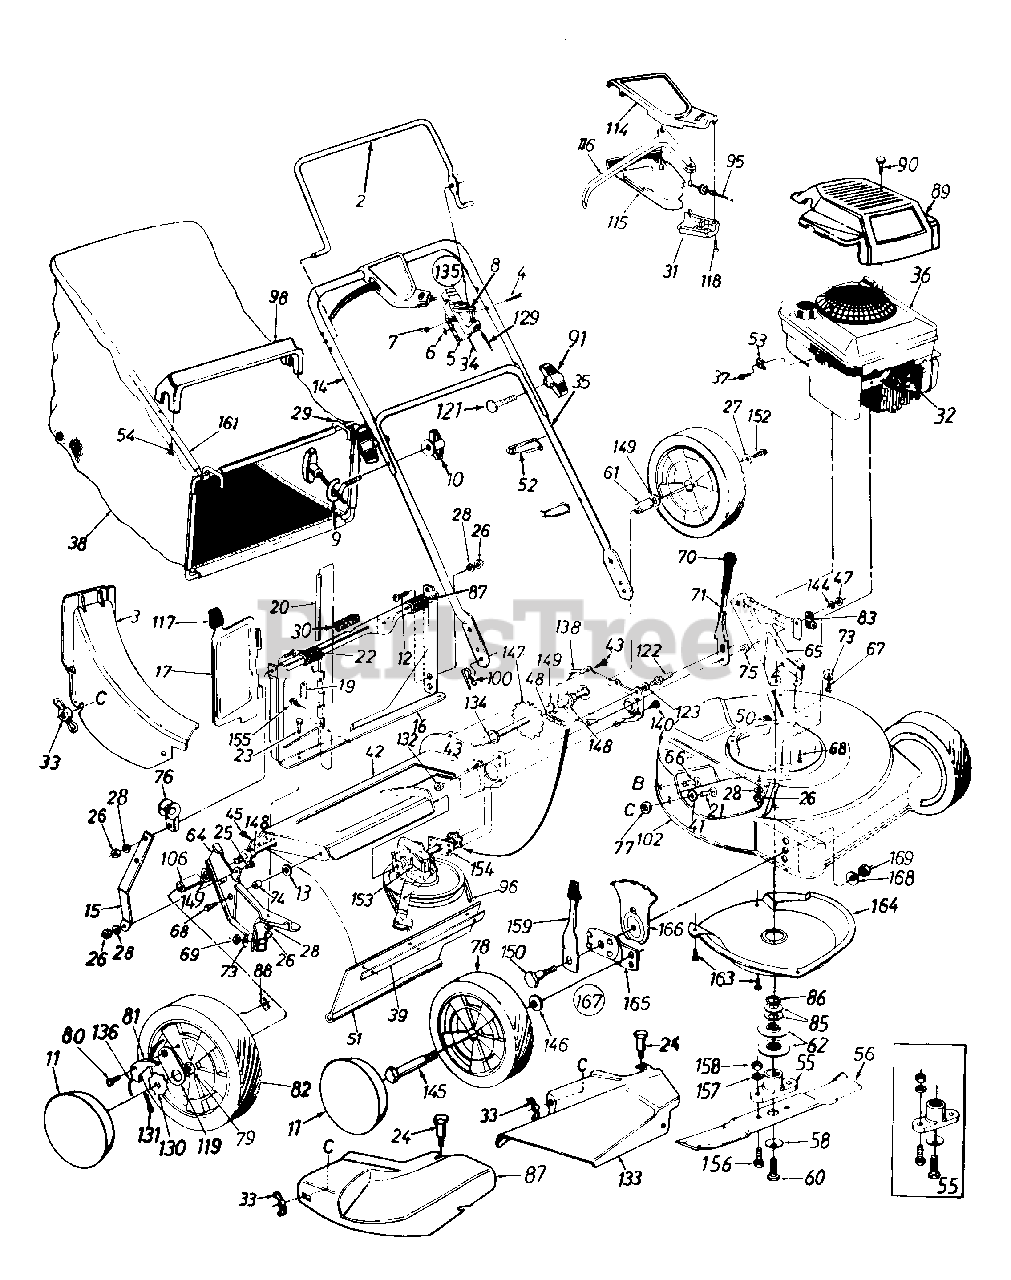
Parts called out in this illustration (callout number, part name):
3	Rear Discharge Chute Ass'y.
4	Oval C-Sunk Scr.
5	Throttle Body
6	Spr. Wash..66" I.D.
7	Hex L-Nut 1/4-20 Thd.
8	Throttle Lever
9	Rope Guide
10	Wing Nut 1/4-20 Thd.
11	Hub Cap
12	Truss Mach. Scr. 1/4-20 x .62"
13	Fl-Wash..383" I.D. x 1" O.D.
19	Torsion Spring
20	Pivot Pin
21	Carriage Bolt 1/4-20 x .62"
22	Truss Mach. Scr. 1/4-20 x 3/4"
23	Hex Bolt 1/4-20 x .50" Lg.
24	Shoulder Bolt .312 Dia. x .18 Lg.
25	Hex Bolt 1/4-20 x .62" Lg.
26	Hex Nut 1/4-20 Thd.
27	Bell-Wash. 1/4" I.D.
28	L-Wash. 1/4" I.D.
30	Foam Strip
31	S.P. Control Cover
32	Spark Plug Insulator
33	Wing Nut w/Washer
34	Throttle Control Wire 61"
37	Hex Self-Tap Scr. #10-32 x .62"
38	Grass Bag
39	Retaining Strip
41	Fl-Wash..344" I.D. x.62"
42	Chain - Axle Ass'y.
43	Hex 8-Tap Scr. 1/4" x .38" Lg.
45	Hex AB-Tap Scr. 1/4 x .62"
47	Hex Patch L-Nut 3/8-24 Thd.
48	#48 Chain .500" Pitch x 30 Links
51	Rear Flap 3.75" x 17.30" Lg.
52	Cable Tie
53	Cable Clamp
54	Hex AB Scr. #12 x 1.25" Lg.
55	Blade Adapter Kit
56	21" Mulching Blade
58	Bell-Wash..46" I.D.
60	Hex Bolt 3/8-24 x 1.5" Lg. (Grade 5)
61	Spacer .513" I.D. x .703" O.D. x .69" Lg.
62	Pulley Half O.D. x .69" Lg.
64	R.H. Handle Wheel Brkt. Ass'y.
65	L.H. Handle Wheel Brkt. Ass'y.
66	Carriage Bolt 5/16-18 x .62"
67	Hex Wash. Hd. B-Tap Scr. 5/16-18
68	Hex Wash. Hd. TT-Tap Scr. 3/8-16
69	Hex Nut 5/16-18 Thd.
71	Height Adj. Lever
73	Bell-Wash. 5/16" I.D.
74	Spacer
75	Shld. Spacer .500" Dia.
76	Rope Guide
77	Bolt Retainer 1/4 x .50" O.D.
78	Front Wheel Ass'y. Comp.
79	Bearing 1/2" I.D.
80	Shld. Scr..342" Dia. x .268
81	Pawl
82	Rear Wheel Ass'y. Comp.
83	Clamp
85	Bell-Washer 1.01" I.D.
86	Crankshaft Spacer
87	Panel Clip
88	Weld L-Nut 1/4-20 Thd.
89	Engine Shroud
90	Screw #10 x 1.25" Lg.
91	Hand Knob
95	S.P. Cable
96	"V"-Belt
98	Bag Handle
114	Self-Propelled Control Cover
115	Self-Propelled Control Cover
116	Control Lever
117	Door Grip
118	Fl-"C"-Sunk Hd. Tap Scr. #10 x .75" Lg.
119	Pawl Plate
121	Curved Carr. Bolt 5/16-18 x 2" Lg.
122	Shld. Pin 3/8-24 x 1.43" Lg.
123	L-Wash. 3/8" I.D."
129	Control Cable 47" Lg.
130	Ratchet Wheel 1.62" O.D.
131	Cotter Pin 1/8" Dia. x 1.00" Lg.
132	Hex Jam Nut 3/8-24 Thd.
133	Side Chute Deflector Ass'y.
134	Hex Flange Bearing
135	Throttle Box Comp.
136	Spring - Nylon
144	Fl-Wash..385" I.D. x .87"
145	Axle Bolt
146	Bell-Wash..4" I.D. x .88" O.D.
147	Rear Shaft Ass'y. 21.94" Lg.
148	Hex Flange Bearing .506" I.D. Plastic
149	Fl-Wash..531" I.D. x.930"
150	Shld. Bolt .5" Dia. x .434"
152	Hex Bolt 1/4-20 x .62" Lg. (Grade 5)
153	Transmission Comp. (See Breakdown)
155	Hex B-Tap Scr. #10 x .38
156	Hex Scr. 3/8-24 x 1.0" Lg.
157	L-Wash. 3/8" I.D.
158	Hex Nut 3/8-24 Thd.
159	Spring Lever Ass'y. w/knob
163	Hex Wash. Hd. Tap Scr. 1/4 x .5" Lg.
166	Height Adj. Plate
167	Front Height Adj. Ass'y. Comp.- R.H.
168	Bell-Wash..39" I.D. x 1.38" O.D.
169	Hex Nut 3/8-16 Thd.
